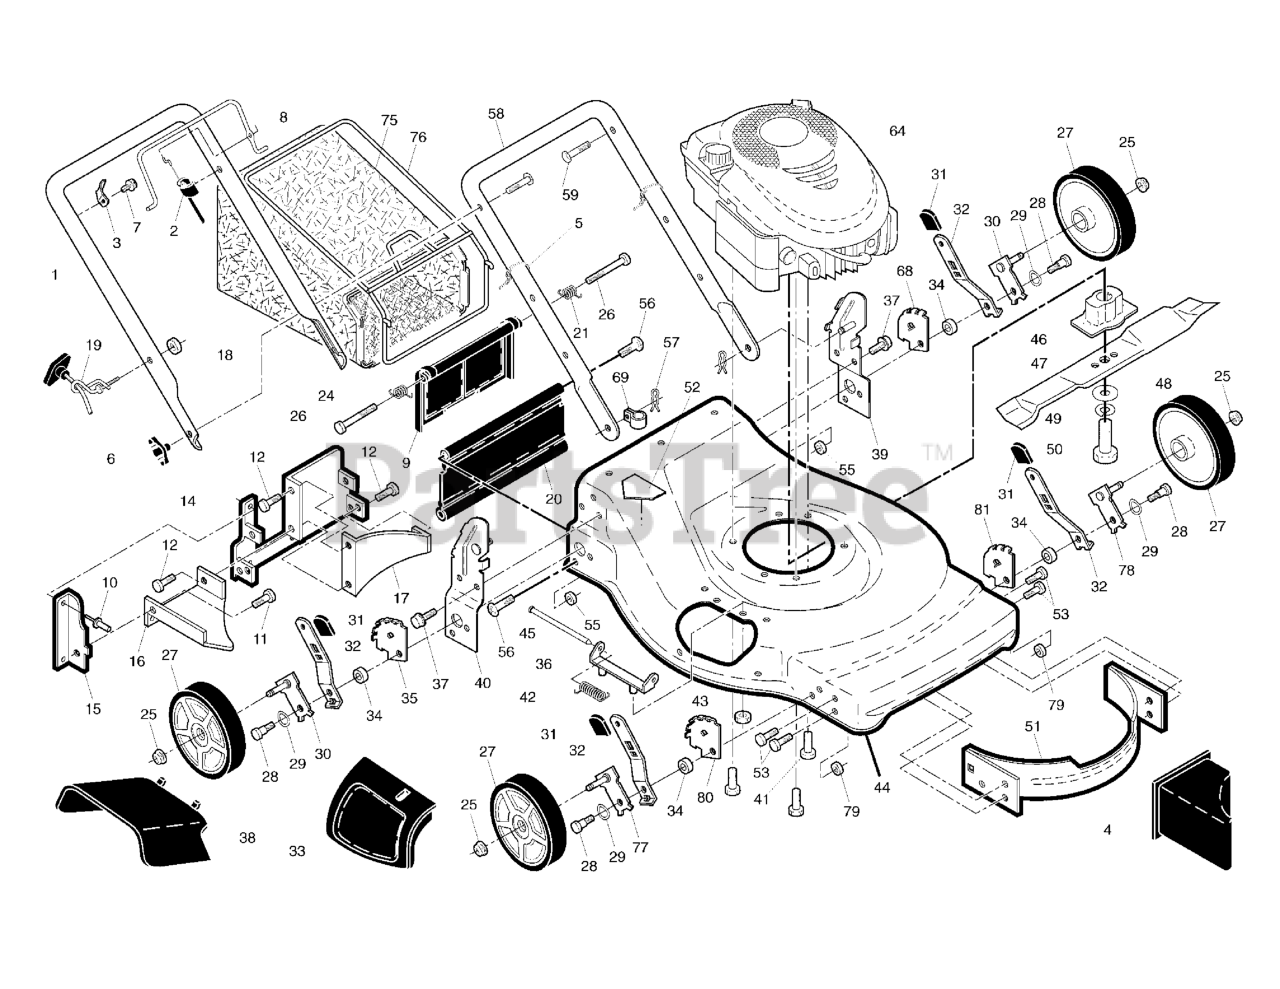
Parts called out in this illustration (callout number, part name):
1	Upper Handle
2	Engine Zone Control Cable
3	Bracket, Upstop
4	Mulcher Plug
5	Wire Tie
6	Handle Knob
8	Control Bar
9	Rear Door Assembly
10	Pop Rivet
11	Screw, Self-Tapping, #10-24 x 5/8
12	Screw, Hex Head, Sems, 1/4-20 x 1/2
14	Back Plate
15	Side Baffle
16	Discharge Baffl e
17	Rear Baffle
18	Keps Locknut 1/4-20
19	Rope Guide
20	Rear Skirt
21	Spring, Rear Door, LH
24	Spring, Rear Door, RH
25	Nut, Hex, Flanged
26	Bolt, Rear Door
27	Wheel & Tire Assembly
28	Bolt, Shoulder 3/8-16 x 1
29	Washer, Curved, Cylindrical
30	Axle Arm Assembly, Rear
31	Selector Knob
32	Selector Spring
33	Mulcher Door
34	Spacer
35	Wheel Adjusting Bracket, Rear, RH
36	Hinge Bracket Assembly
37	Screw
38	Discharge Defl ector
39	Handle Bracket Assembly, LH
40	Handle Bracket Assembly, RH
41	Screw, Hex Head, Threaded, Rolled, 3/8-16 x 1-1/8
42	Spring, Torsion
43	Nut, Hex, Nylock
44	Kit, Mower Housing (Includes Ref. Nos. 14, 15 & 51)
45	Rod, Hinge
46	Blade Adapter
47	Blade, 22"
48	Washer, Hardened
49	Washer, Helical
50	Screw, Machine, Hex Head, 3/8-24 x 1-3/8, G8
51	Kit, Front Baffle (Includes Ref. No. 53)
52	Danger Decal
53	Screw, Serrated, TT 1/4-20
55	Nut, Hex 3/8-16
56	Hinge Screw 1/4-20 x 1-1/4
57	Hairpin Cotter
58	Lower Handle
59	Handle Bolt
64	* Engine, Briggs & Stratton
68	Wheel Adjusting Bracket, Rear, LH
69	Clip, Cable
75	Grassbag Assembly
76	Frame, Grassbag
77	Axle Arm Assembly, Front, RH
78	Axle Arm Assembly, Front, LH
79	Locknut, Hex 1/4-20
80	Wheel Adjusting Bracket, Front, RH
81	Wheel Adjusting Bracket, Front, LH
